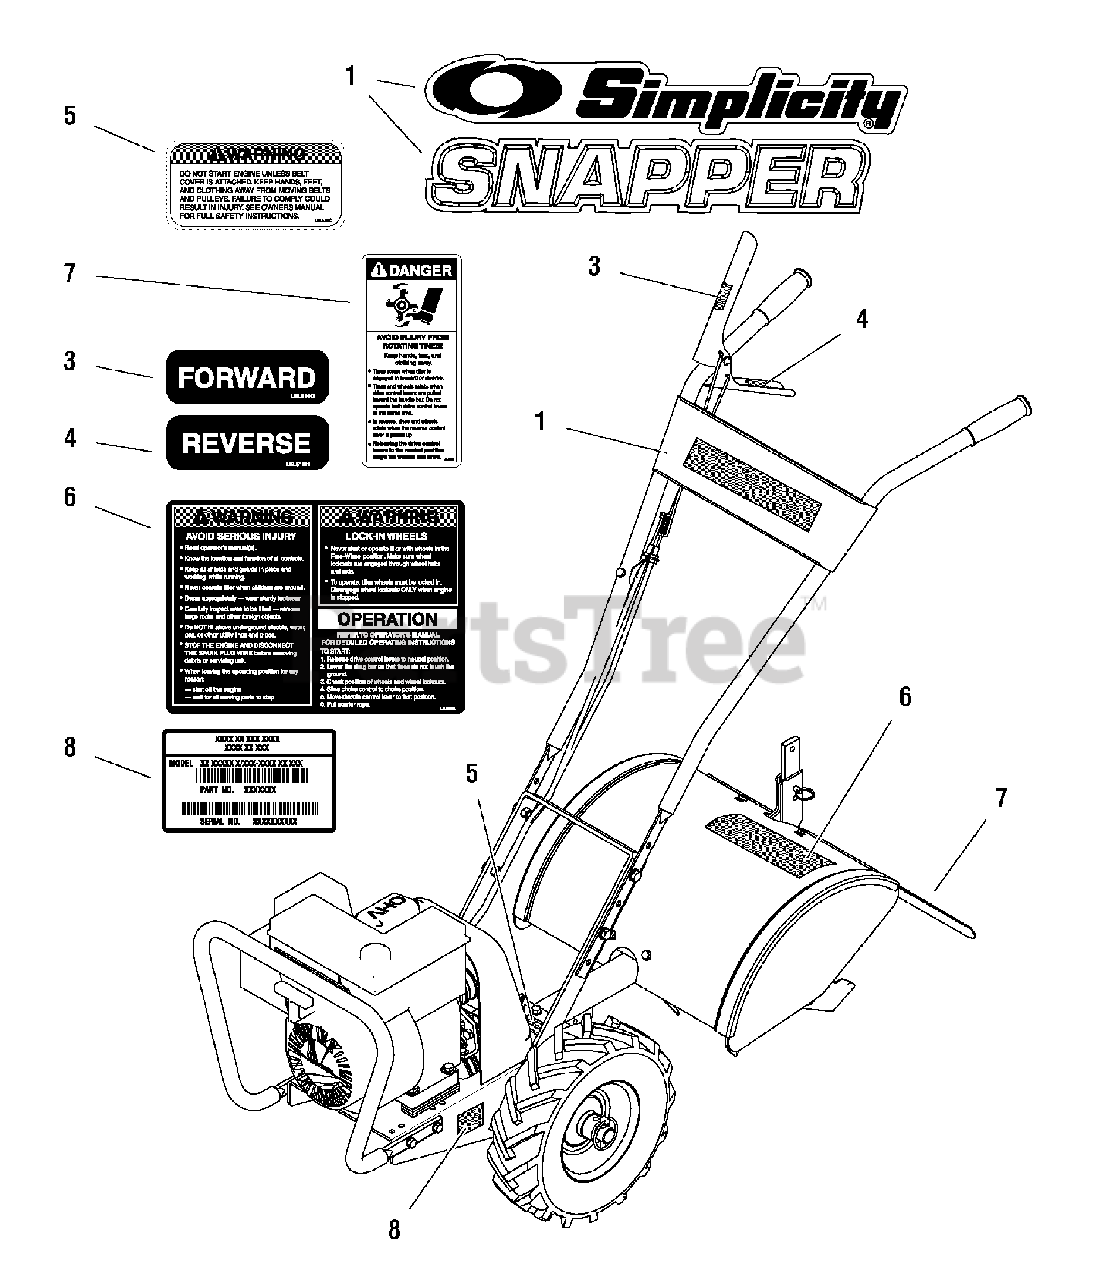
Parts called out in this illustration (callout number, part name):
1	DECAL, SIMPLICITY, w/Logo
1	DECAL, Snapper
2	DECAL SHEET, Common Warning, Tillers
3	* DECAL, Forward Instructions
4	* DECAL, Reverse Instructions
5	* DECAL, Warning, Belt Cover
6	* DECAL, Hood, Operator Instructions Label
7	* DECAL, Danger, Rotating Tines
8	** DECAL, Serial Number
